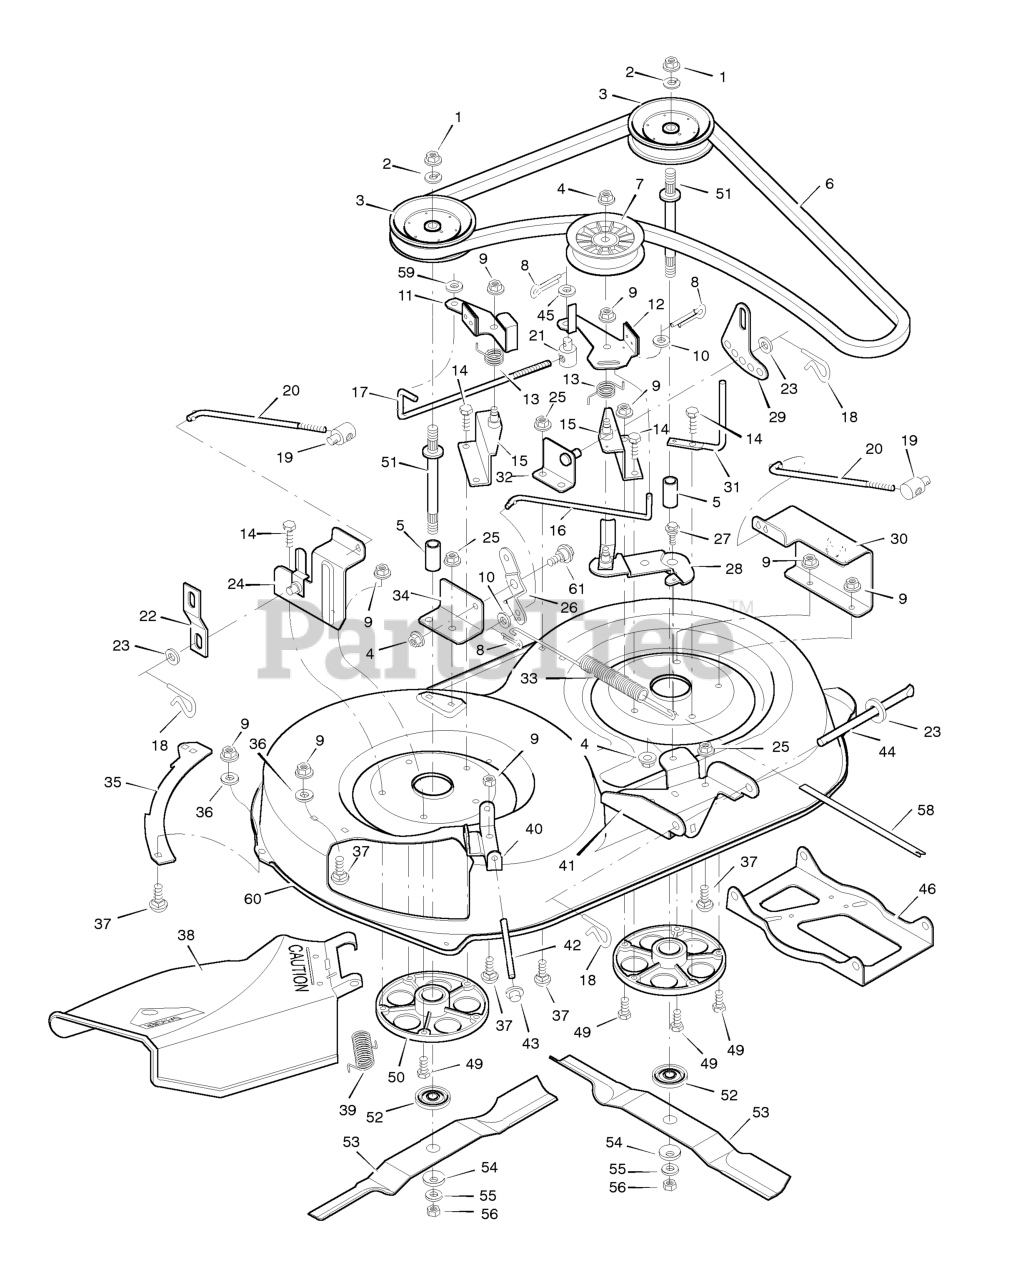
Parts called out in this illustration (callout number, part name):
1	Nut, Hex
2	Lockwasher
3	Pulley, Jackshaft
4	Locknut, Flange
6	Belt, Blade Drive
7	Pulley, Idler
8	Pin, Cotter
9	Locknut, Flange
10	Washer
11	Brake Assembly, Right
12	Brake Assembly, Left
13	Spring, Torsion
14	Bolt, Hex
15	Bracket Assembly, Brake
16	Rod, Brake
17	Rod, Cross Link
18	Pin, Hair
19	Nut, Adjustable
20	Rod, Adjuster
21	Nut, Adjustable
22	Link, Suspension
24	Bracket Assembly, Right Lifter
25	Nut, Flange
26	Bracket, Pivot
27	Bolt, Shoulder
28	Arm Assembly, Idler
29	Plate, Adjuster
30	Cover, Pulley
31	Guide, Belt
32	Bracket Assembly, Left Lifter
33	Spring, Extension
34	Bracket, Pivot
35	Plate
37	Bolt, Carriage
38	Deflector Assembly, Chute
39	Spring, Torsion
40	Bracket, Hinge
41	Bracket, Front Hanger
42	Rod, Deflector
43	Cap, Push On
44	Rod, Hanger
46	Hanger, Front
49	CAPSCREW, Hex Head, 5/16-18 x 1
50	Housing, Jackshaft
51	Jackshaft
52	Adapter, Blade
53	Blade, 38" (2 required)
54	Washer, Belleville
56	Nut, Hex
58	Indicator, Plastic
60	Housing, Blade (38")
61	Bolt, Shoulder
